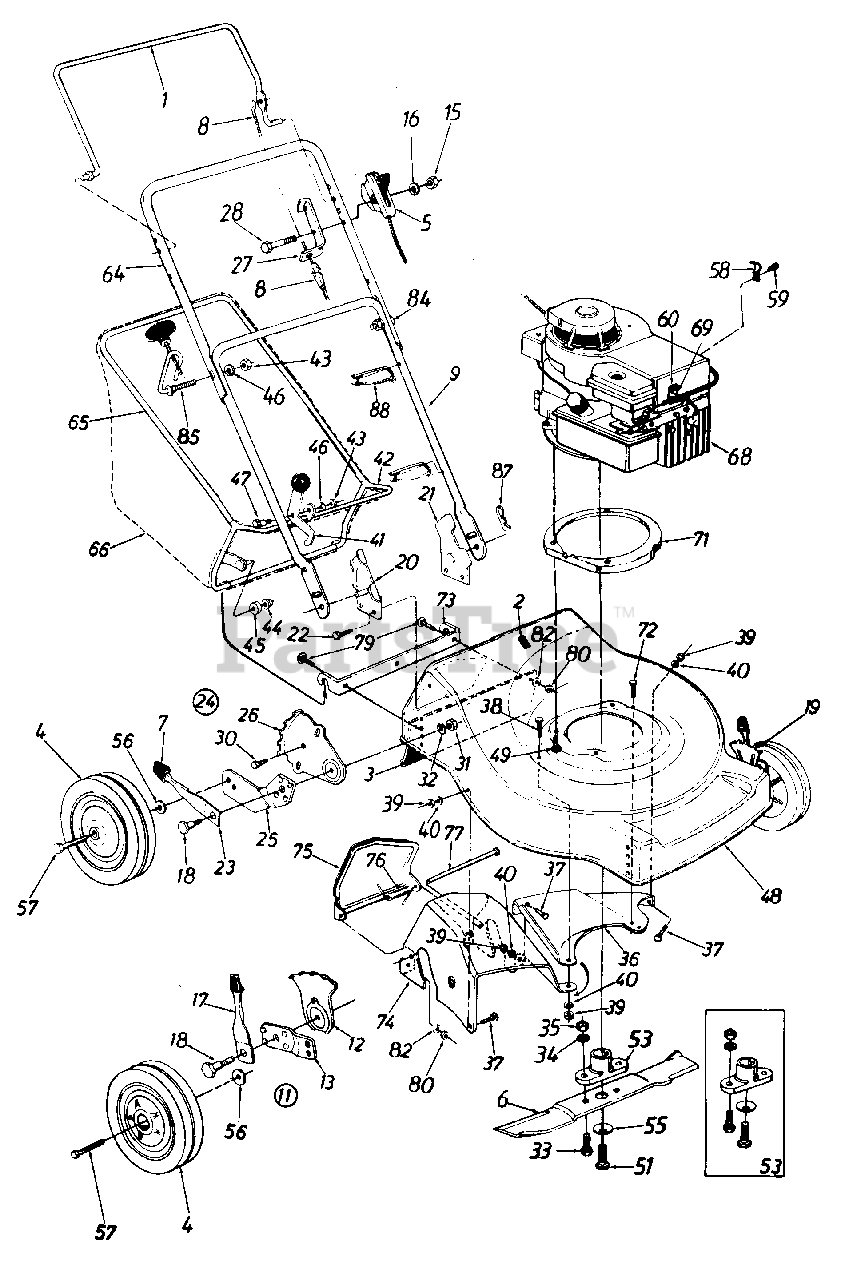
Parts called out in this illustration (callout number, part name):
1	Control Handle Ass'y.
3	Rear Flap Ass'y.
4	Wheel Ass'y. Comp.
5	Throttle Control Ass'y. Comp.
6	20" Blade
7	Spring Lever Knob
8	Control Cable-43"
9	Lower Handle
11	Front Height Adj. Ass'y.-R.H.
12	Front Index Plate
15	Hex Nut 1/4-20 Thd.
16	Spr. Wash. .265" I.D.
17	Spring Lever w/Knob
18	Shld. Bolt .50" Dia. x .375
19	Front Height Adj. Ass'y.-L.H.
20	Handle Brkt. Ass'y.-R.H.
21	Handle Brkt. Ass'y.-L.H.
22	Hex Wash. Hd. AB-Tap Scr. 1/4 " x .62" Lg
23	Spring Lever
24	Rear Height Adj. Ass'y.-R.H.
25	Rear Pivot Bar-R.H.
26	Rear Index Plate
27	Cable Mounting Bracket
28	Hex Bolt 1/4-20 x 1.75" Lg.
30	Hex Wash. Hd. Tap Scr. 1/4 x 62" Lg.
31	Hex Nut 3/8-16 Thd.
32	Bell-Wash. 3/8" I.D.
33	Hex Bolt 3/8-24 x 1 "
34	L-Wash. 3/8" I.D.
35	Hex Nut 3/8-24 Thd.
36	Rear Chute Baffle-L.H.
37	Carr. Bolt 1/4-20 x 50" Lg.
38	Hex Bolt 1/4-20 x .88" Lg.
39	Hex Nut 1/4-20 Thd.
40	L-Wash. 1/4" I.D.
41	Cam Lever Grip Ass'y.
42	Grass Catcher Lower Frame
43	Hex Nut 5/16-18 Thd.
44	Push Cap 3/8" Rod
45	Plastic Roller
46	L-Wash. 5/16" I.D.
47	Shld. Bolt .437" Dia. x .180"
51	Hex Bolt 3/8-24 x 1.5" Lg. (Grade 5)
53	Blade Adapter Kit
55	Bell-Wash..39" I.D.
56	Bell-Wash. .400" I.D. x .88"
57	Axle Bolt
58	Cable Clip
59	Hex AB-Tap Scr. #10 x .38"
60	Casing Clamp
64	Upper Handle
65	Grass Catcher Upper Frame
66	Grass Bag
68	Engine
69	Hex AB-Tap Scr. #8 x .38" Lg.
71	Engine Mounting Cover
72	Hex Self-Tap Scr. 1/4-20 x .75n
73	Grass Catcher Hitch Brkt.
74	Rear Chute Baffle-R.H.
75	Chute Door
76	Torsion Spring
77	Hinge Pin
79	Carr. Bolt 1/4-20 x .75" Lg.
80	Hex Sems Nut 1/4-20 Thd.
82	Fl-Wash. .281" I.D. x 1.25"
84	Curved Carr. Bolt 5/16-18 x 1.38" Lg.
85	Rope Guide Bolt
87	Hairpin Cotter
88	Cable Tie
